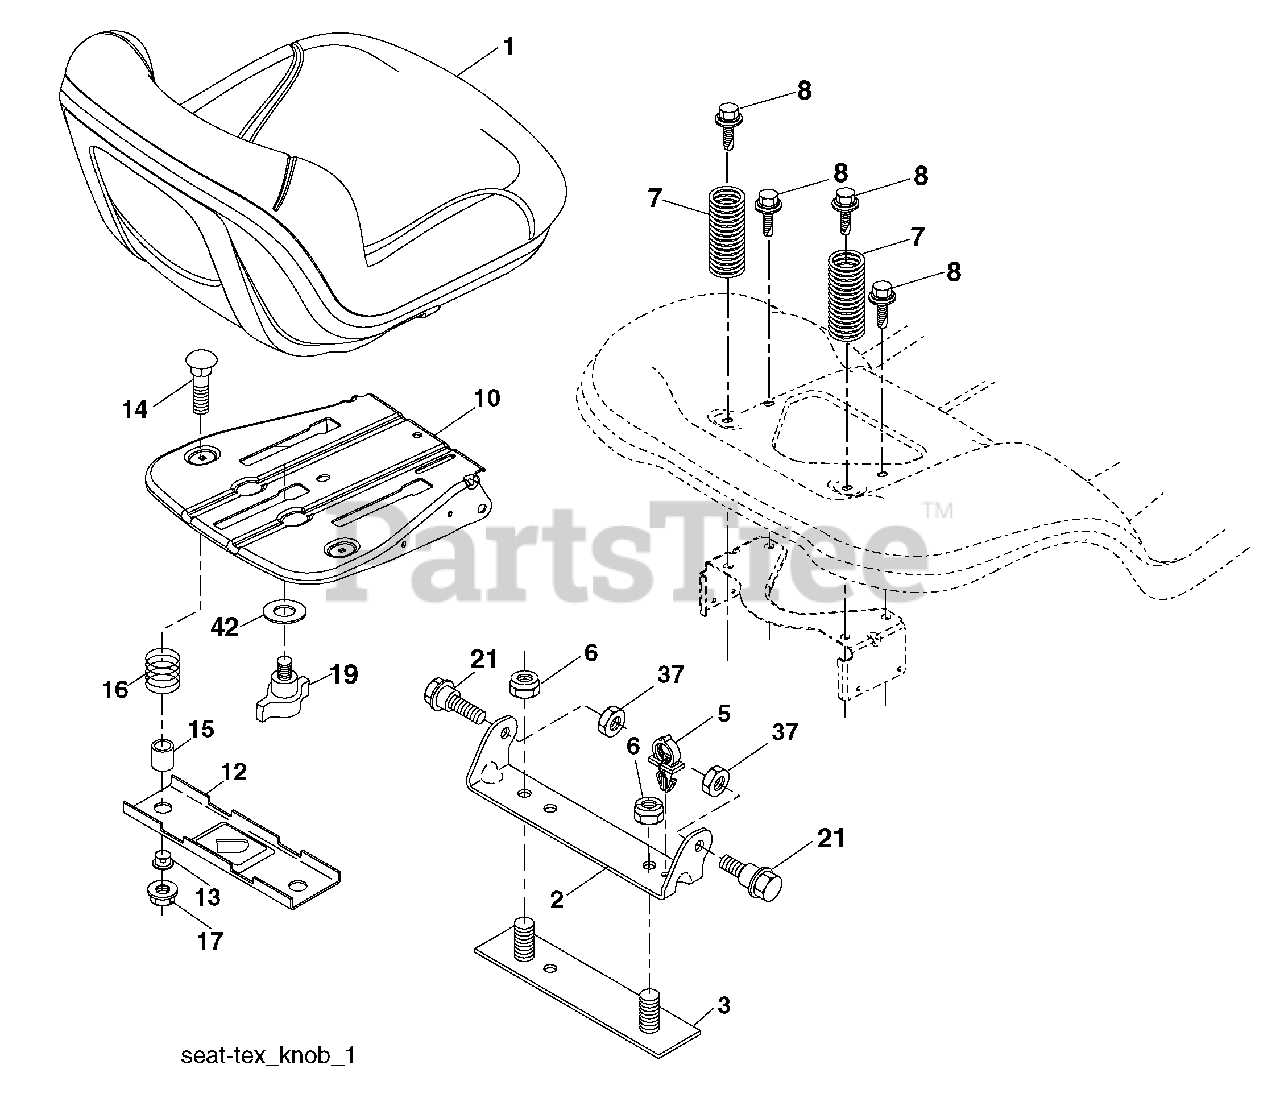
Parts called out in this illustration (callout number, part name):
1	Seat
2	Bracket Pivot Fender
3	Strap, Asm Fender
5	Clip, Push In, Hinged
6	Nut, Lock w/Ins. 3/8-16 unc
7	Spring, Seat Cprsn
8	Bolt 5/16-18 unc x 3/4 w/Sems
10	Pan, Seat
12	Bracket Mnt Seat
13	Bushing Snap
14	Bolt 1/4-20 x 1/2
15	Spacer Split
17	Nut Lock 1/4
21	Bolt, Shoulder 5/16-18
37	Nut, Lock 5/16-18 unc
42	Washer Cup Seat
